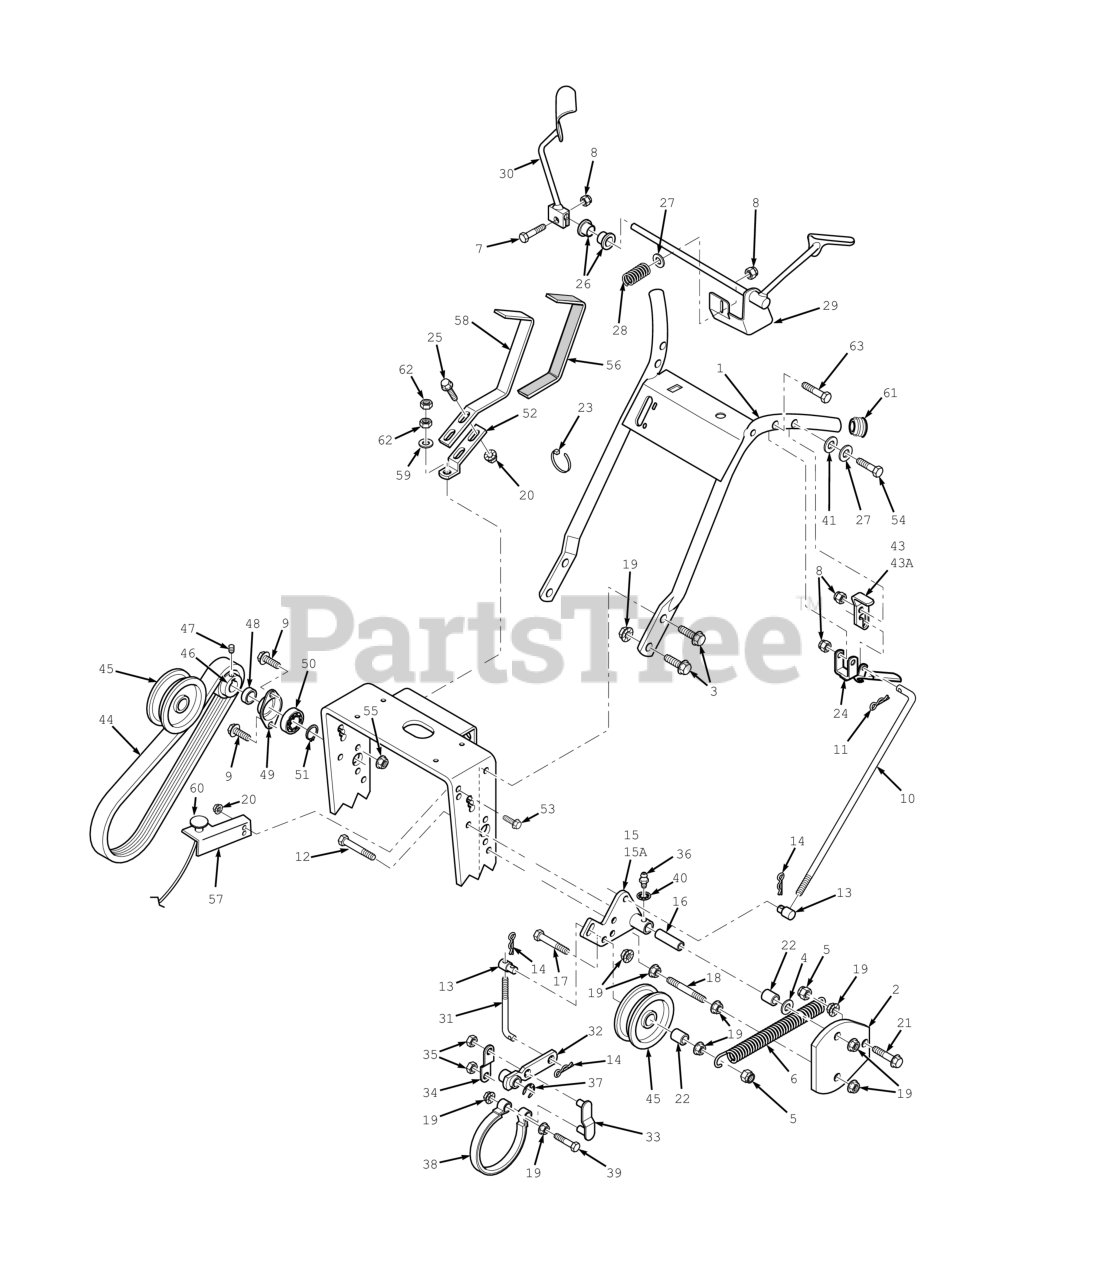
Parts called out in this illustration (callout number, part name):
1	Handle Assembly
2	BELT GUARD
3	Capscrew, 3/8-16 x 1.0" Serrated Flange Hex Hd
4	Flatwasher, 3/8" Special (.391 x .938 x .105)
5	HEX NUT, ELASTIC STOP LOCK, 3/8-16
6	Spring,Counter Balance
7	Bolt, 5/16 - 18 x 1 - 1/4" Hex Head
8	HEX NUT, ELASTIC STOP LOCK, 5/16-18
9	Bolt, Serrated Flange Hex Head 1/4 x 20 x 3/4"
10	Control Rod, Steering
11	HAIR PIN, .08 DIAMETER X 1-3/16"
12	Bolt, 3/8 - 16 x 4 - 1/2" Hex Head
13	SWIVEL JOINT, SPEED CONTROL ROD
14	COTTER PIN, HAIR - 0.94 X 1.62
15	Idler Bracket, RH
15A	Idler Bracket, LH
16	IDLER SLEEVE
17	Capscrew, Hex Head 3/8-16 x 3.25"
18	SUPPORT BELT GUARD
19	NUT, 3/8-16 SERRATED FLANGE HEX HEAD
20	Nut, Serrated Flange 5/16-18 (Right Front Engine Mounting, Briggs and Kohler Only)
21	CAPSCREW, 3/16 X 1-1/4" SERRATED FLANGE
22	Spacer, Idler
23	Cable Tie, .19 x 8.0"
24	Lever, Steering Control
25	Cpscrw, 5/16-18 x 1"Serrated Flange Hex Head
26	Bushing
27	Flatwasher, 5/16-.375 x .875 x .083 (35BV & 37BV-EFI)
28	Spring, Operator Presence
29	Operator Presence Lever, LH
30	Operator Presence Lever, RH
31	BRAKE ROAD
32	BRAKE LEVER
33	Link Weldment, Brake
34	BRAKE LINK PLATE
35	Nut, 3/8 Push - on
36	Greese Fitting, Straight 1/4 - 28
37	RETAINING RING, 5/8" EXTERNAL "E"
38	Brake Band Assembly
39	Capscrew, Hex Head 3/8-16 x 2.0"
40	1/4" INTERNAL TOOTH LOCKWASHER
41	Socket Head Capscrew #8-32 x 1/2"
42	Socket Head Capscrew #8 - 32 x 1/2"
43	Neutral Latch-RH 461241 Neutral Latch-LH
43A	Neutral Latch Assembly, LH
44	BELT, WHEEL DRIVE
45	Idler Pulley, Wheel Drive
46	Pulley, Jackshaft
47	Setscrew, Hex Socket Knurl Cup Pt. 5/16 - 18 (nylock)
48	SPACER, JACKSHAFT PULLEY
49	FLANGE, JACKSHAFT BEARING
50	BEARINGS, BALL, NEUTRAL RETURN
51	RETAINING RING, 5/8 EXT. - BASIC
52	Shift Lever
53	Capscrew, 5/16-18 x .75 Serrated Flange Hex Head
54	Bolt, Hex Head 5/16-18 x 2-1/2" (x3) (35BV & 37BV-EFI)
55	NUT, 1/4-20 SERRATED FLANGE HEX HEAD
56	Grip, Shift Handle
57	Bracket, Choke Mounting
58	Shift Lever Extension w/Grip
59	Flatwasher, 3/8" Special (.391 x .938 x .105)
60	Choke Control
61	Plug, Handle Bar
62	HEX NUT, 3/8-24 R.H. THREAD
63	Bolt, Hex Head 5/16-18 x 2-1/2" (35BV & 37BV-EFI)
64	Cap, Fuel Tank
